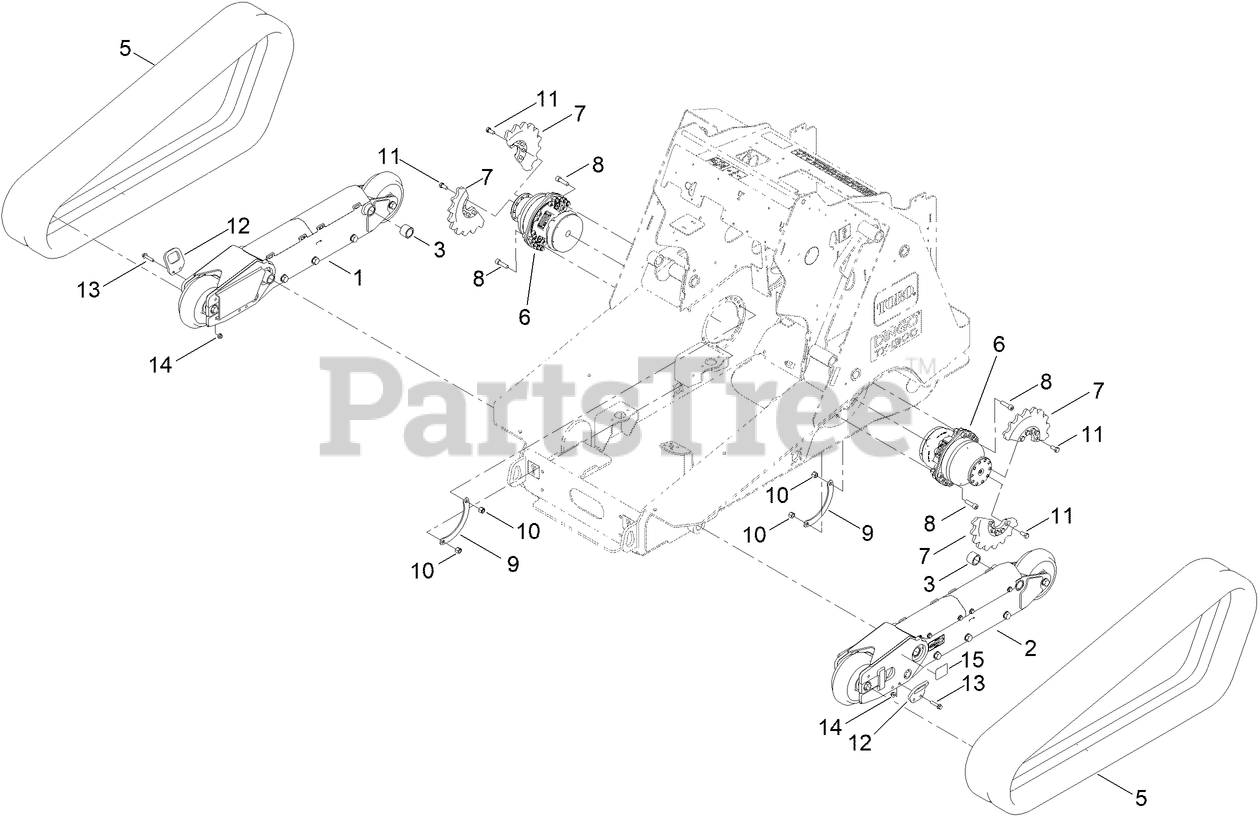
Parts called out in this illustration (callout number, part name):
1	TRACK ASM-RH
2	TRACK ASM-LH
3	SPACER
5	TRACK-WIDE,
6	WHEELMOTOR ASM
7	SPROCKET-DRIVE
8	SCREW-HSH
9	PLATE-COVER
10	NUT-LOCK, NI
11	SCREW-HH
12	PLATE-TIE DOWN
13	SCREW-HHF
14	NUT-HF, NI
15	DECAL-TIE DOWN
